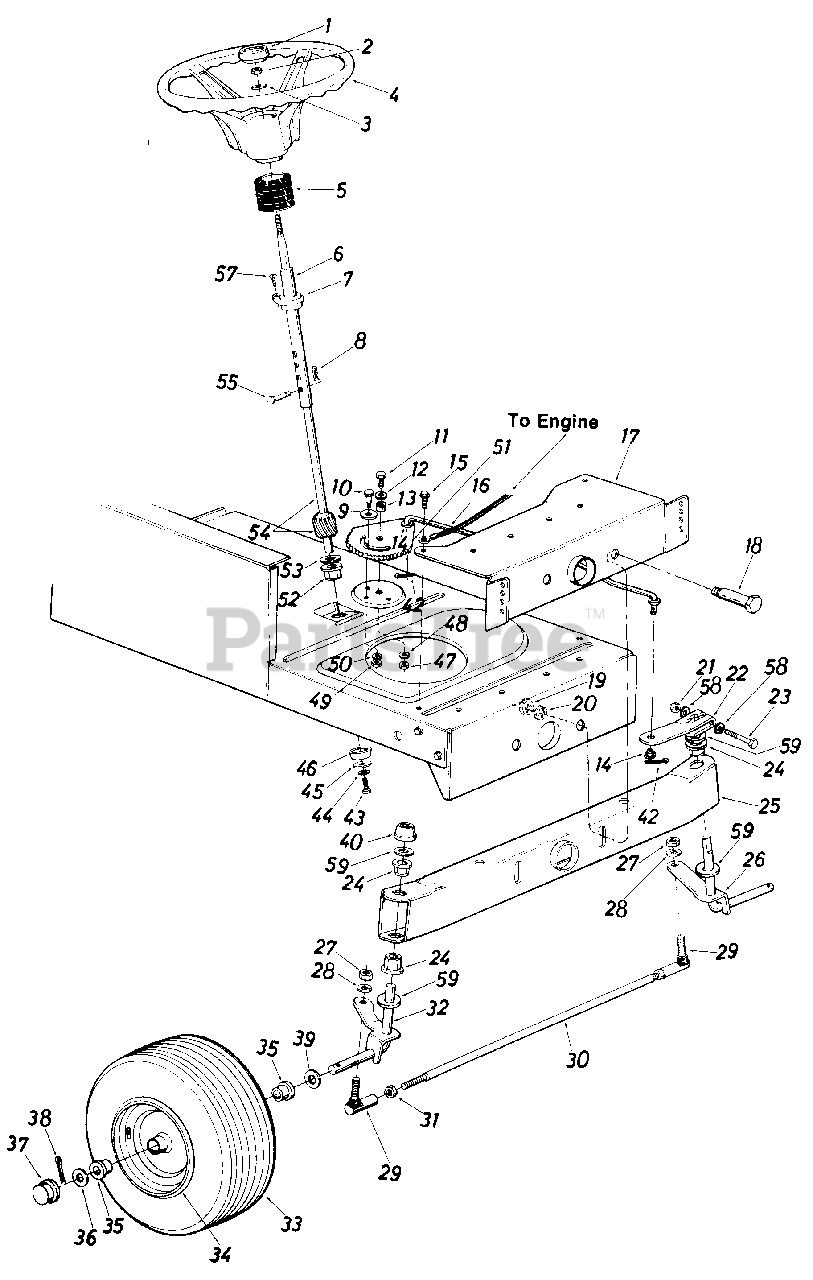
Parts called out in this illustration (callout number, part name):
1	Steering Wheel Cap
2	Hex Nut 5/16-18 Thd.
3	Belleville Wash. .345" I.D.
4	Steering Wheel
5	Steering Bellow 4.5"
6	Steering Column Ass'y.
7	Flange Bearing .890 I.D. x 1.36 O.D.
8	Internal Cotter Pin 1/4" Dia.
9	Fl-Wash. .438" I.D. x 1.37" O.D.
10	Shoulder Bolt .437" Dia. x .35 Lg. 5/16-18 Thd.
11	Hex Bolt 3/8-24 x 1.0" Lg. Grade 5
12	Fl-Wash. .38" I.D. x 1.0" O.D.
13	Spacer.380" I.D. x .625" O.D. x .227
14	Bushing
15	Hex Wash. Hd. Self-Tap Scr.
16	Steering Drag Link
17	Front Pivot Brk't.
18	Shoulder Bolt .498" Dia. x 2.04 Lg. 3/8-16 Thd.
19	Hex Nut 3/8-16 Thd.
20	L-Wash. 3/8" I.D.
21	Hex Cent. L-Nut 5/16-24 Thd.
22	Steering Arm Front Axle
23	Hex Bolt 5/16-24 x 2.00" Lg. Grade 5
24	Hex Flg. Brg. .634 I.D.
26	Front Axle Ass'y. L.H .
27	Hex Nut 3/8-24 Thd.
28	L-Wash. 3/8" I.D.
29	Bal I Joint 3/8-24 Thd.
30	Tie Rod
31	Hex Jam Nut 3/8-24 Thd.
32	Front Axle Ass'y. R.H.
33	Wheel Ass'y. Comp.
34	Front Wheel Rim Only
35	Bearing
36	Fl-Wash. .635 I.D. x 1.59" O.D.
37	Front Wheel Hub Cap
38	Cotter Pin 1/8n Dia. x 1.25" Lg.*
39	Fl-Wash. .635" I.D. x 1.20" O.D.
40	Push Cap 5/8" Dia. Rod
42	Cotter Pin 1/8" Dia. x 1.0"
43	Hex L-Bolt 5/16-18 x .62" Lg.
44	L-Wash. 5/16" I.D.
45	Fl-Wash. .344n l.D. x 1.25" O.D.
46	Spacer (Plastic)
47	Hex Nut 3/8-24 Thd.
48	L-Wash. 3/8" I.D.
49	Hex Nut 5/16-18 Thd.
50	L-Wash. 5/16" I.D.
51	Steering Gear Segment
52	Hex Flg. Brg. .634 I.D.
53	Fl-Wash. (Hardened)
54	Steering Shaft Lower
55	Clevis Pin 1/4" Dia. x 1.00" Lg.
57	Oval Hd. Cr. Sunk Scr. #10 x 5/8" Lg.
58	Bell-Wash.
59	Fl-Wash. (Hardened)
